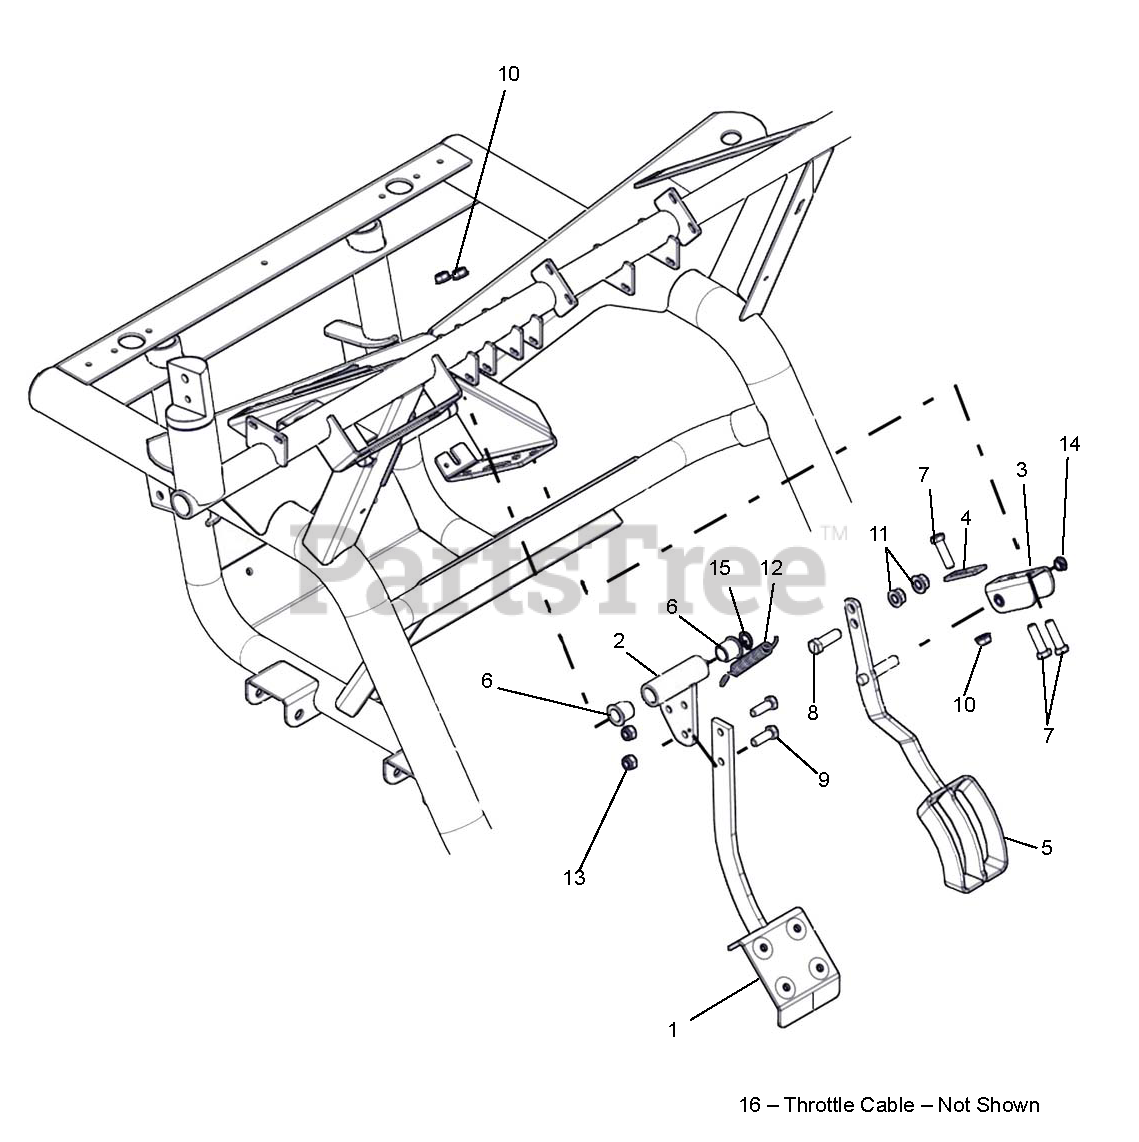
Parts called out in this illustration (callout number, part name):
1	BRAKE PEDAL ASM
2	BRAKE PEDAL PIVOT WELDMENT
3	GAS PEDAL MOUNT
4	GAS PEDAL ADJUSTMENT PLATE
5	WLDT, GAS PEDAL
6	BUSHING 3/4ODX5/8IDX3/4 FLG HD
7	@BLT-HEX .31-18X1.25 GR5 YWZC
8	@BLT-HEX .38-16X1.25 GR5 YWZC
9	@BLT-HEX .31-18X1.00 GR5 YWZC
10	@NUT-LK-TOP-FLG .31-18 YWZC
11	@NUT-LK-TOP-FLG .38-16 YWZC
12	SPRING EXT .5OD .075W 2.75LG
13	@NUT-LK-NYL .312-18 YWZC
14	BUSHING NYLON 3/8ID (SNAP IN)
15	SNAP RING, .625 X .035 EXT
